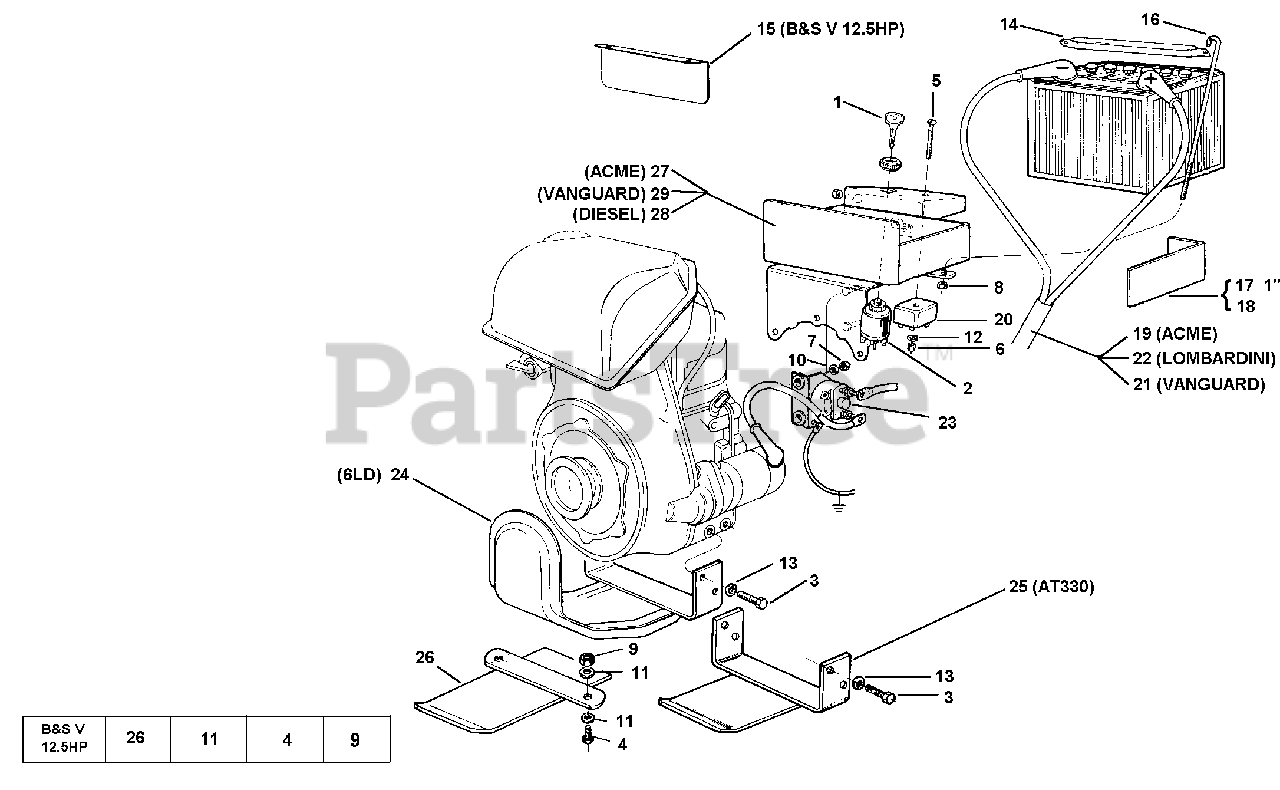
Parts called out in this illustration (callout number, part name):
3	SCREW M8 X 16
4	SCREW M8 X 40
5	SCREW TC M4 X 30 UNI 6107
8	NUT, SELF LOCKING M6
9	NUT, SELF LOCKING M8
10	WASHER, FLAT 6.4
11	WASHER, LOCK 8.4
12	WASHER, LOCK 4.3
13	WASHER, LOCK 8.4
14	BATTERY BRACKET
15	GUARD, BATTERY
16	BATTERY TIEROD
17	SHOCK PROOF RUBBER
18	ANTISHOCK BAT
19	ELEC. START CABLES MC 715
21	ELECTRIC STARTER CABLES B&S
22	ELECTRIC STARTER WIRES
23	BOSCH RELAY 0332002160
25	ENGINE GUARD
26	GUARD B&S 12.5HP
27	BATTERY SUPPORT
28	BATTERY SUPPORT
29	BATTERY SUPPORT
